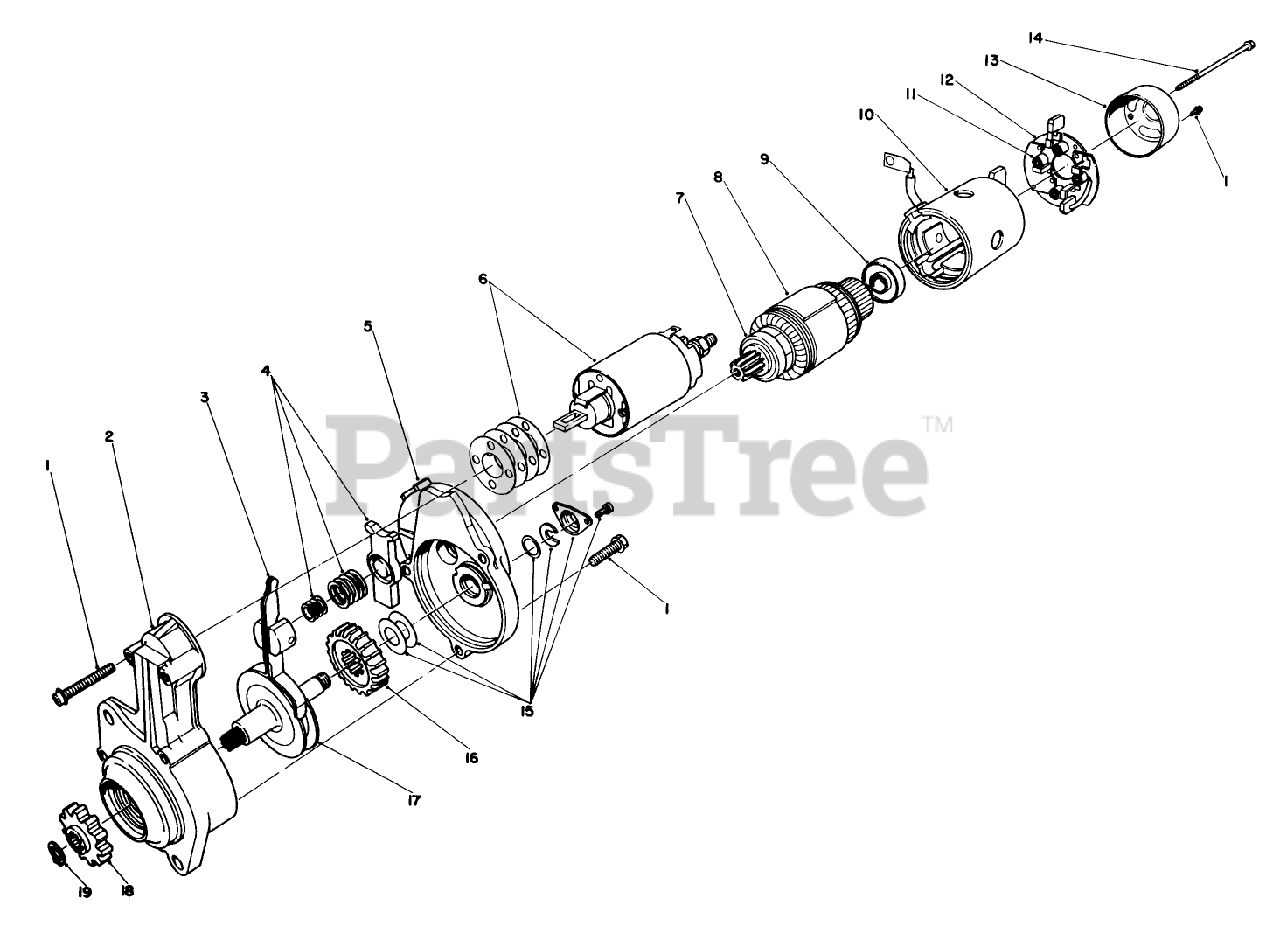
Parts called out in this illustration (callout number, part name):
1	Screw Set
2	Bracket Assembly, Front
3	Lever Assembly
4	SPRING SET
5	Bracket Assembly Center
6	Switch Assembly
7	Bearing Front
8	Armature Set (Incl. Ref. #7 & 9)
9	Bearing Rear
10	Yoke Assembly
11	BRUSH SPRG
12	Brush Holder Assembly (Incl. Ref. #11)
13	Bracket Rear
15	Cover Set
16	GEAR MD 607458
17	Shaft Assembly Pinion
18	Pinion Set (Incl. Ref. #19)
19	Snap Ring
